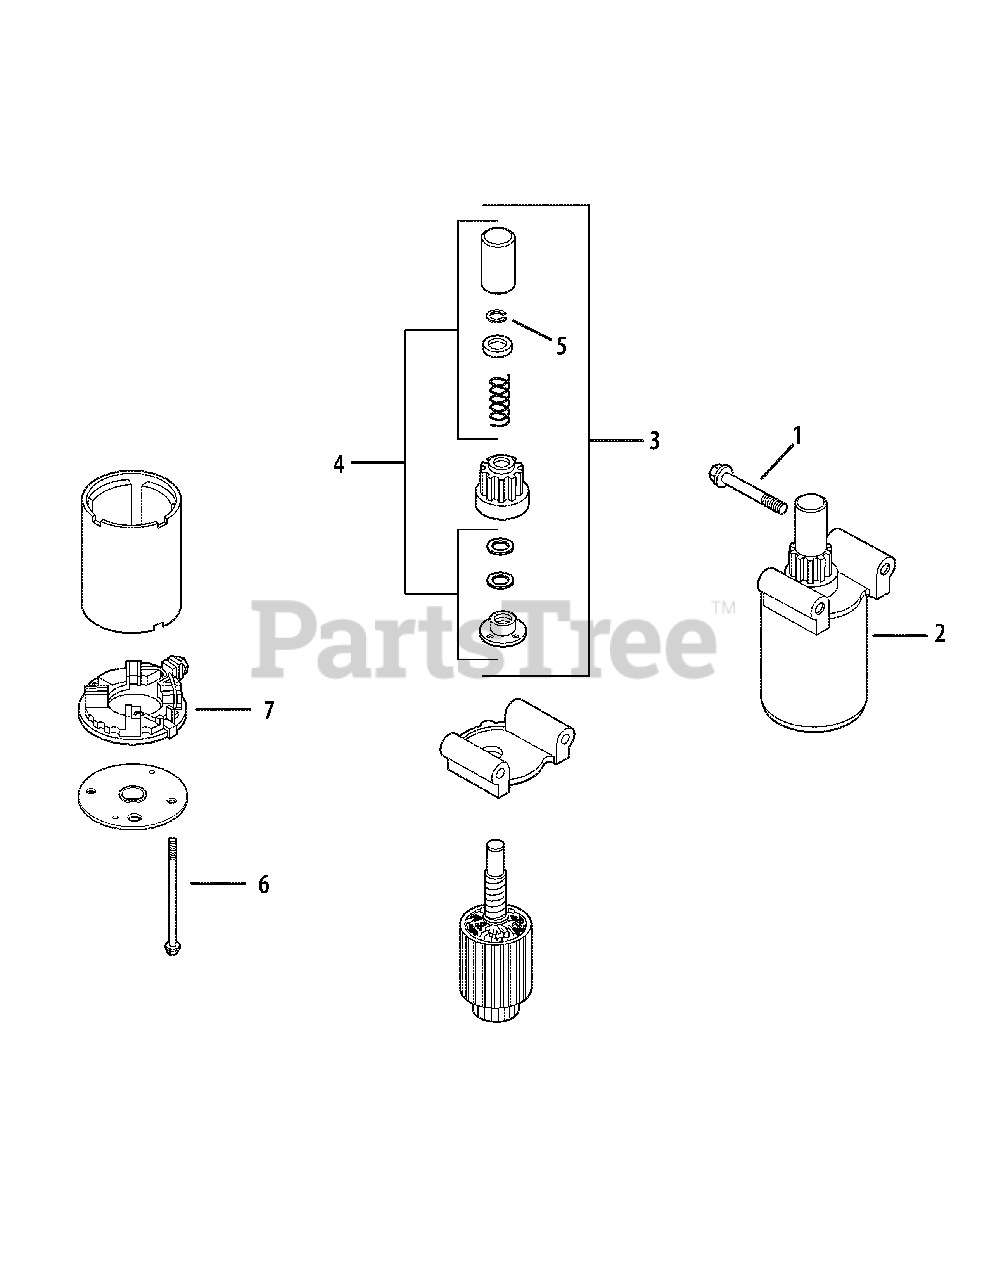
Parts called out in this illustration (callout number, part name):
1	Screw, hex. flange M8x1.25x70
2	Starter assembly
4	Kit, drive parts
5	Retaining Ring
7	Commutator, end cap
